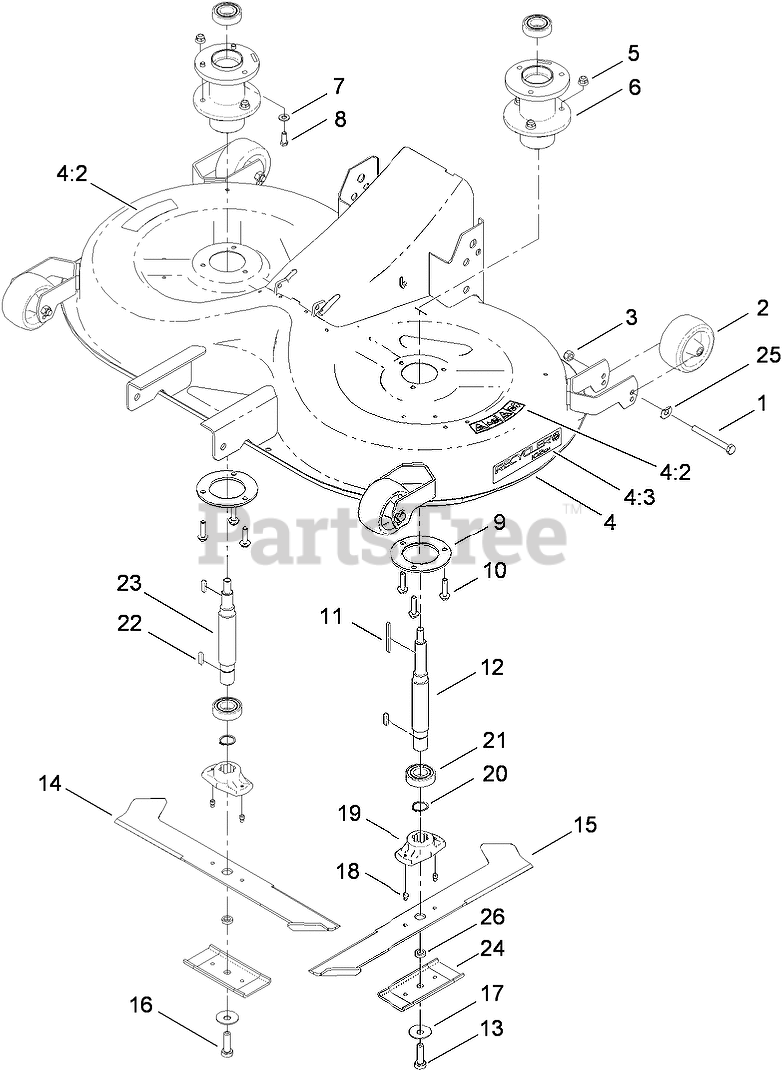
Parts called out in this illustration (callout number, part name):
1	SCREW-HH
2	WHEEL-GAUGE
3	NUT-LOCK, NI
4	DECK ASM
4:2	DECAL-DANGER
4:3	DECAL-RECYCLER
5	NUT-LOCK, HHF
6	HOUSING-SPINDLE
7	WASHER-PLAIN
8	SCREW-HH
9	SUPPORT-RING
10	BOLT-HHF
12	Shaft-Blade, LEFT
13	BOLT-HH
14	BLADE-RH
15	BLADE-LH
16	BOLT-BLADE, HH
17	WASHER-BLADE
18	PIN-SHEAR, GROOVED
19	Adapter-Blade
20	RING-LOCKING
21	BEARING-BALL
22	KEY-SQUARE
23	Shaft-BLADE, Right
24	STIFFENER-BLADE
25	Washer
26	Spacer
